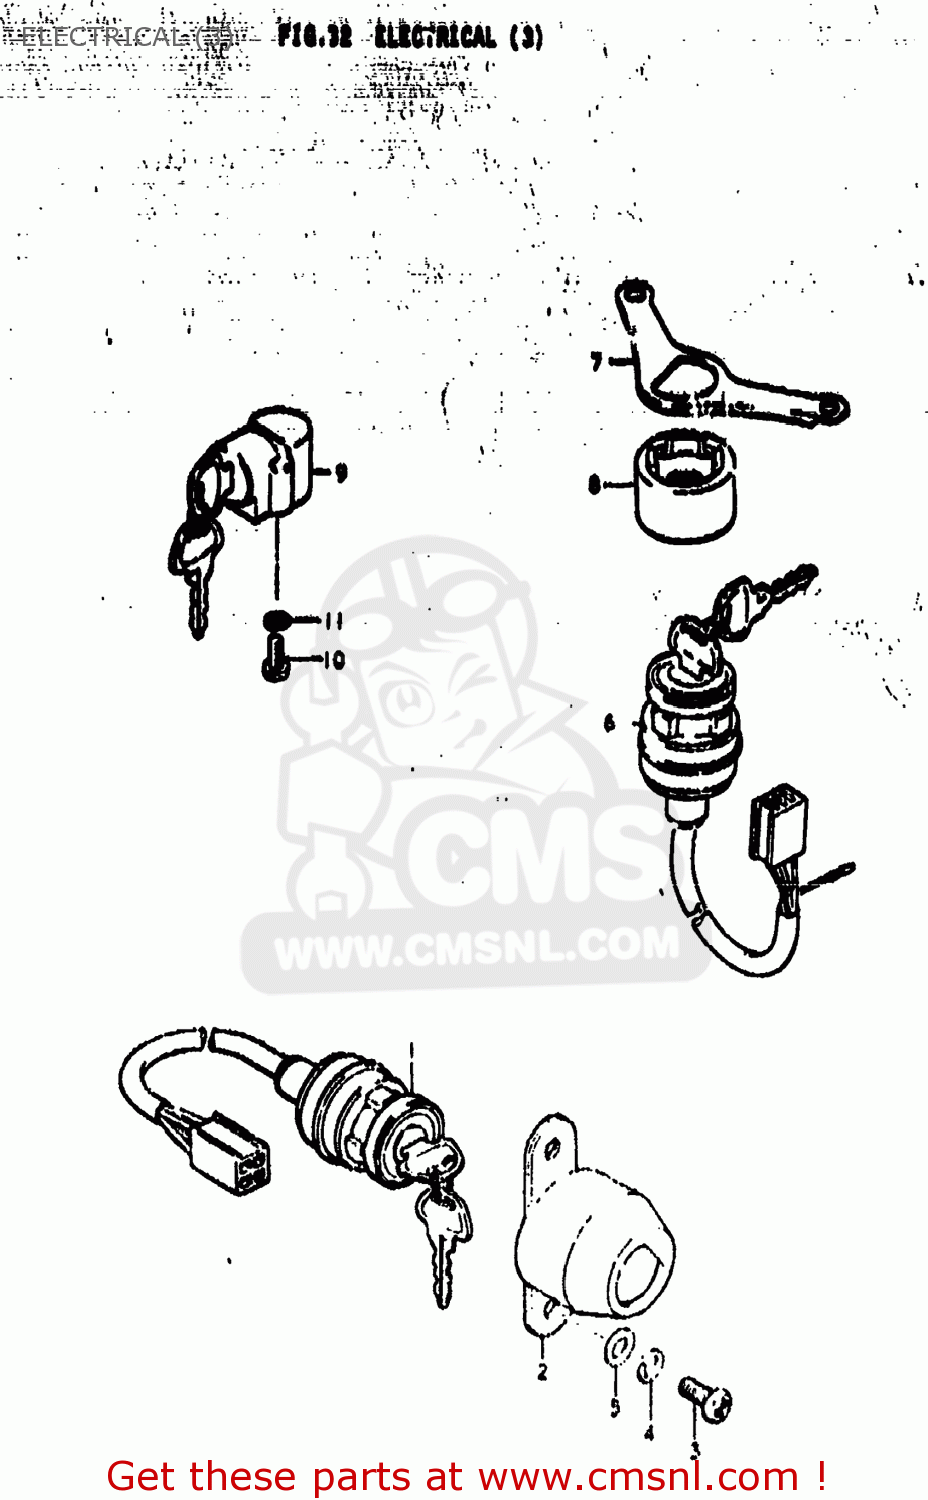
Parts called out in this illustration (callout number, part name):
1	SWITCH ASSEMBLY,IGNITION
2	BRACKET,IGNITION SWITCH
3	SCREW 6X12
4	LOCK WASHER
5	WASHER
6	SWITCH ASSEMBLY,IGNITION
7	BRACKET,IGNITION SWITCH
8	IGN SWITCH COVE
9	LOCK ASSEMBLY,STEERING
10	Screw
11	LOCK WASHER
